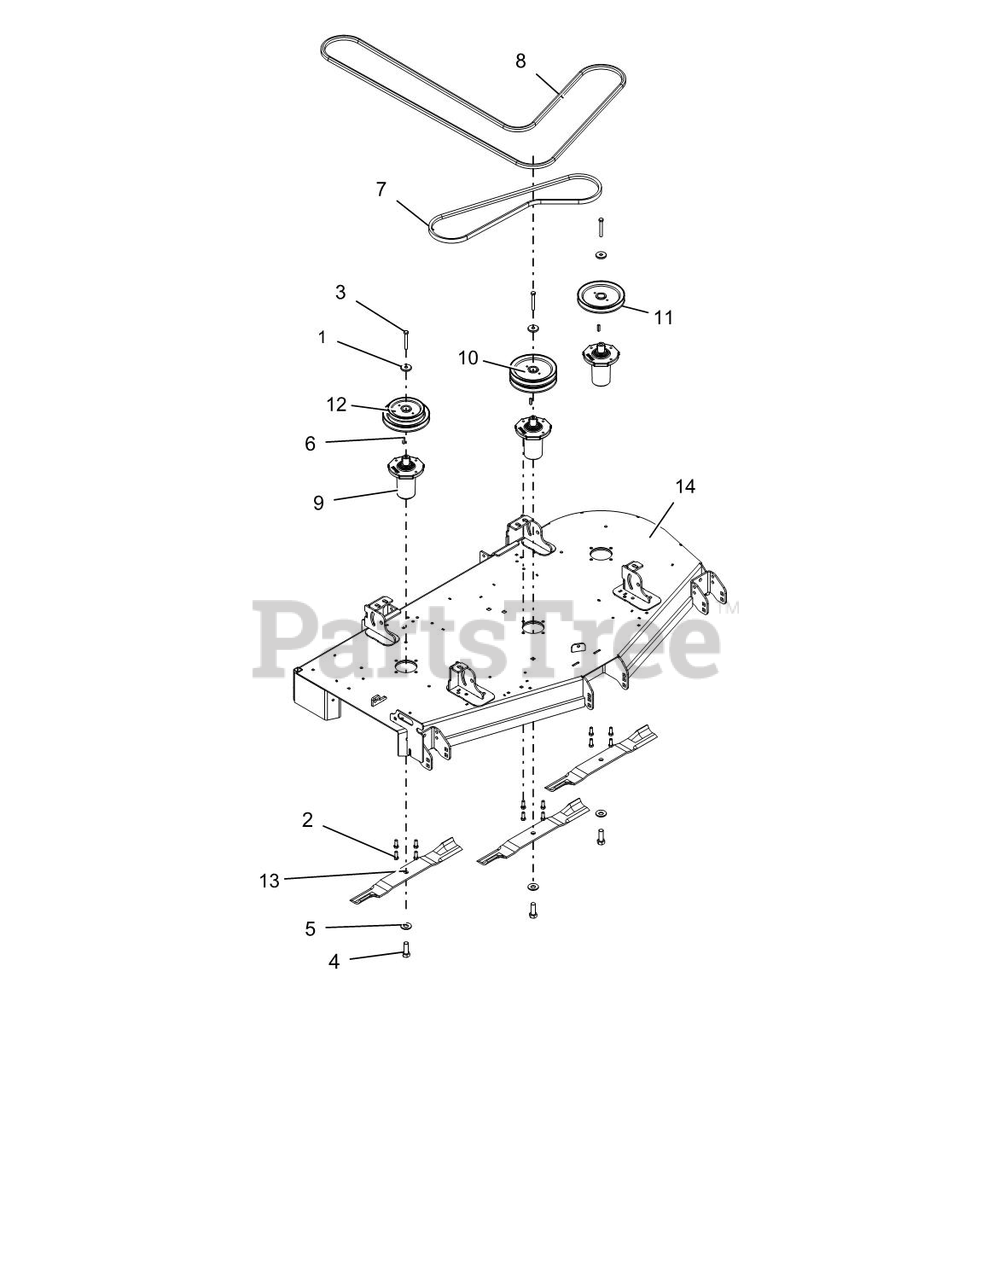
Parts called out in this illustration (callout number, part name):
1	RETAINER, SHEAVE
2	BLT-HEX .38-16X1.0 GR8 YZ EP30
3	BLT-HEX .38-16X2.75 GR8 YWZC
4	BLT-HEX .62-18X1.75 GR8 YWZC
5	WSHR-BLVL .669X1.535X.138
6	KEY, SQ .25X.25X1.00 RC 40-50
7	V-BELT, B-COGGED
8	HEX BELT, BB-WRAPPED
9	ASM, MAINT FREE SPINDLE
10	PULLEY, DOUBLE-1"ID X 6.75"OD
11	PULLEY, V-1" ID X 6.75" OD
12	PULLEY, DBL-1"IDX6.75"&5.25"OD
13	BLADE, MOWER (20.50")
14	KIT-60" MOWER DCK W/SAFE DECAL
